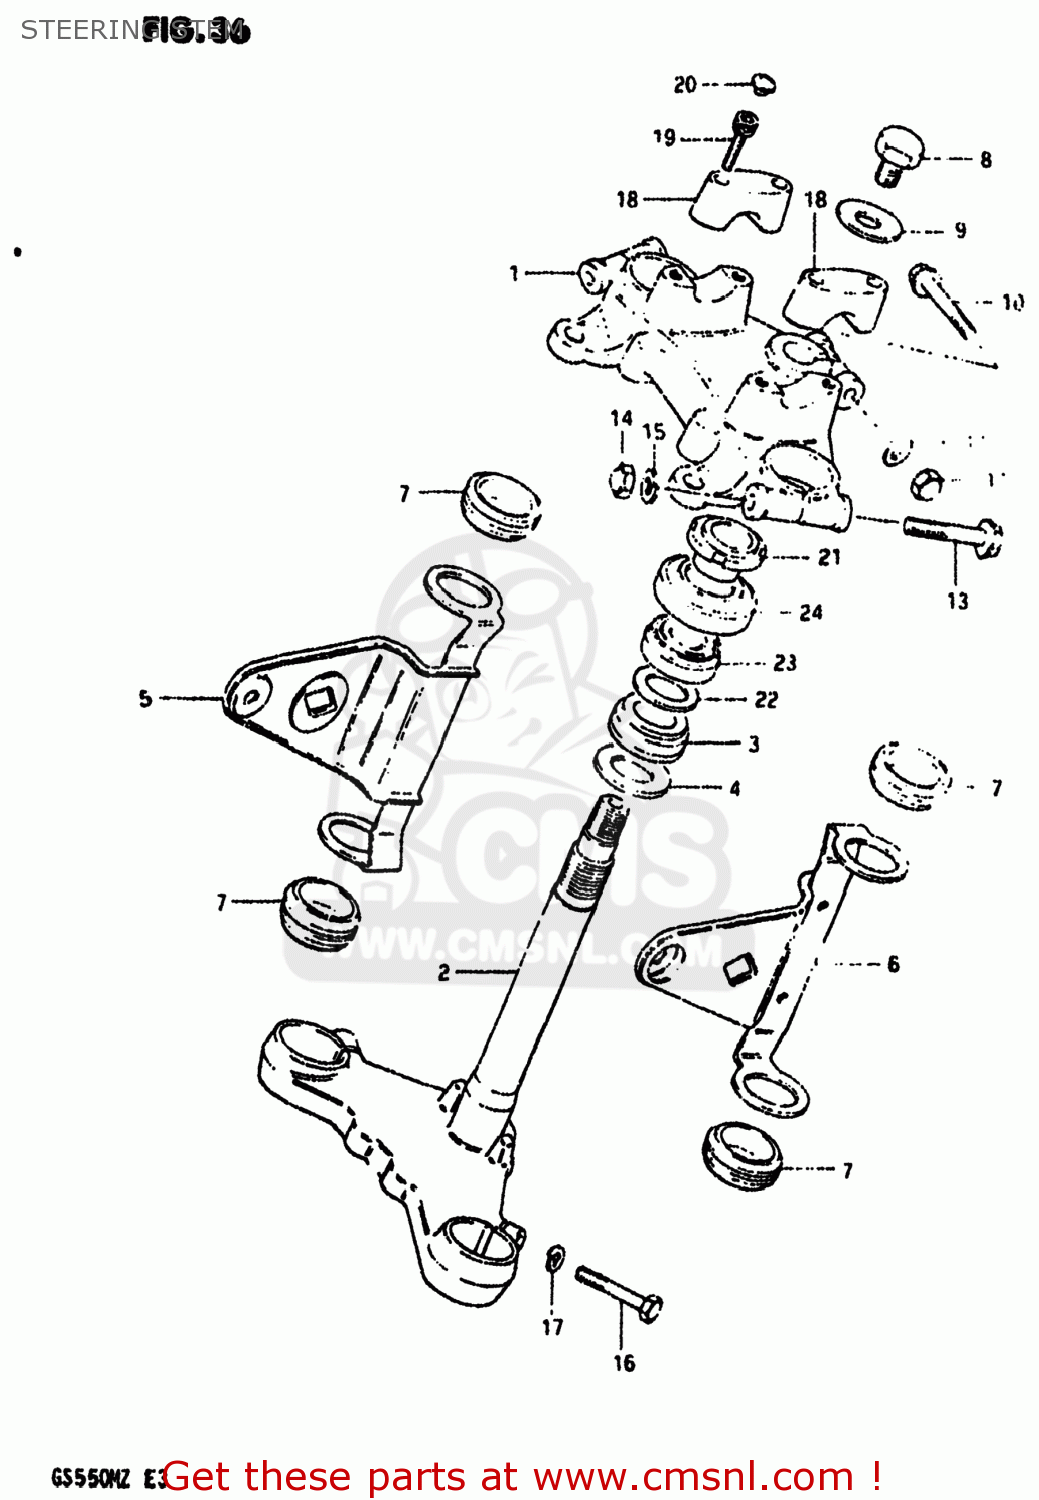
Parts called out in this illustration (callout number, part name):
1	HEAD,STEERING STEM
2	STEM,STEERING
3	BEARING
4	WASHER,THRUST
5	BRACKET,HEADLAMP,RIGHT
6	BRACKET,HEADLAMP,LEFT
7	CUSHION,HEADLAMP BRACKET
8	BOLT 12X20
9	WASHER (12.5X26X1.6)
10	BOLT
11	NUT
12	LOCK WASHER
13	BOLT 10X55
14	NUT
15	LOCK WASHER
16	BOLT 10X40
17	LOCK WASHER
18	HOLDER,HANDLEBAR(BLACK)
19	BOLT
20	CAP(OD:14.5)
21	NUT,STEERING STEM
22	WASHER(18.5X24X1)
23	TAPER,ROLLER BEARING
24	DUST SEAL,STEERING UPR
